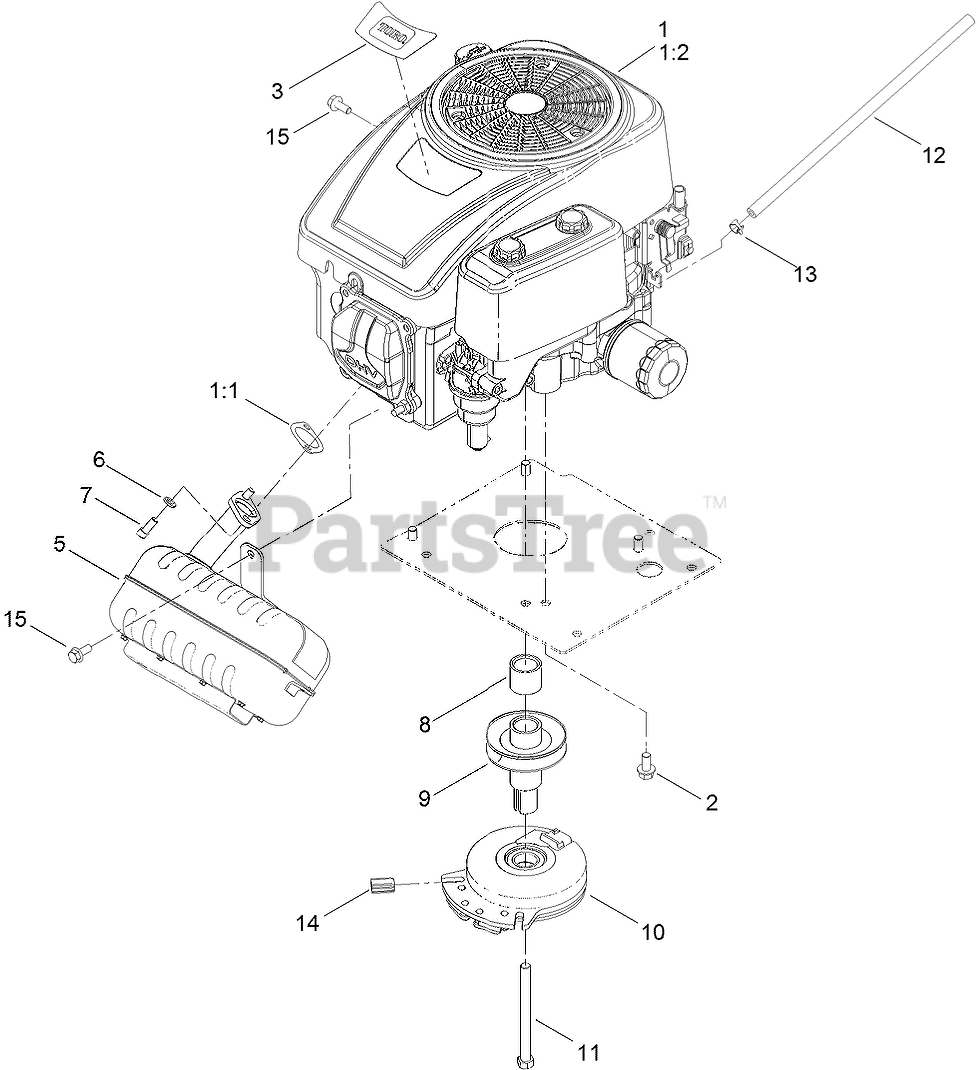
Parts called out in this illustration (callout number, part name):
1	ENGINE ASM
1:1	GASKET-EXHAUST
1:2	ENGINE-LC1P92F-1
2	SCREW-TAPTITE
3	DECAL-ENGINE
5	MUFFLER
6	WASHER-LOCK
7	SCREW-HSH
8	SPACER
9	PULLEY-ENGINE
10	CLUTCH-ELECTRIC
11	SCREW-HH
12	HOSE-FUEL
13	CLAMP-HOSE
14	ISOLATOR-CLUTCH
15	SCREW-HHF
